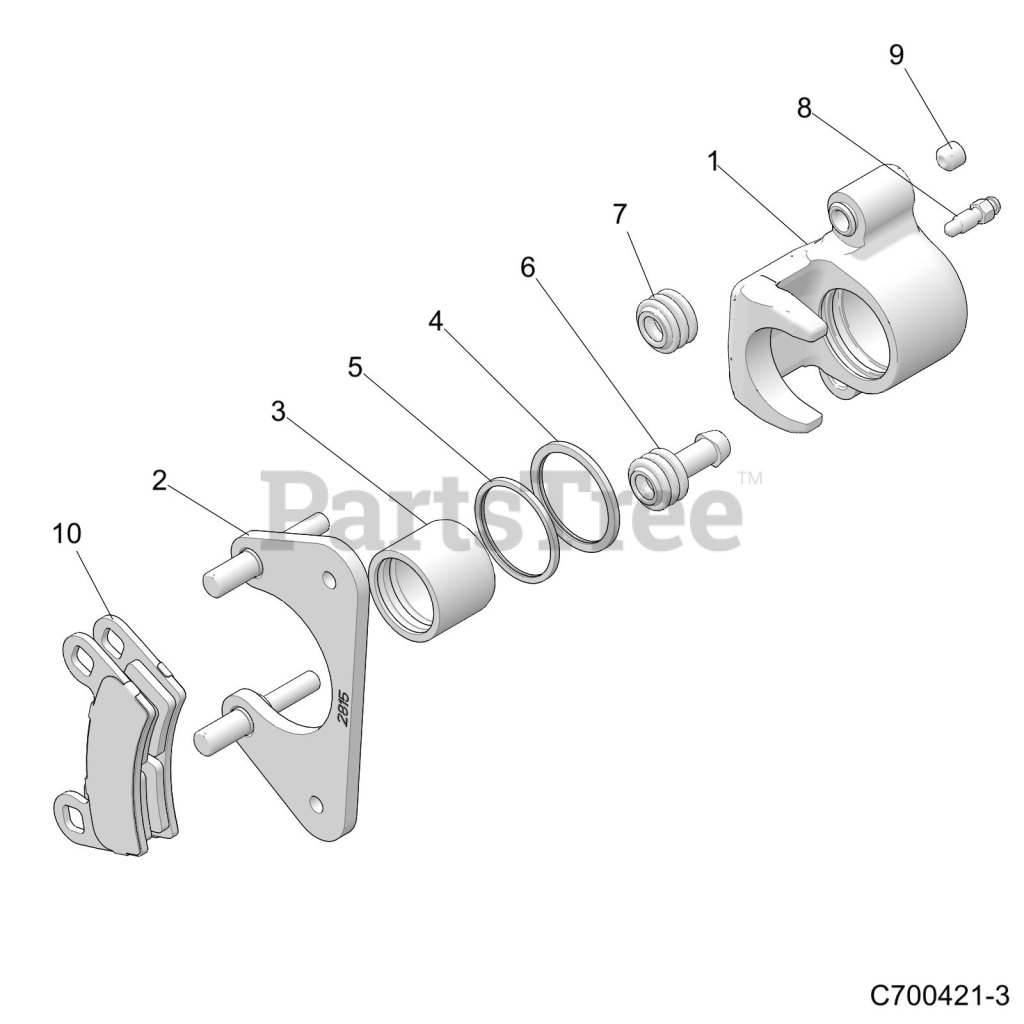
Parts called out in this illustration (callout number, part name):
1	ASM-BRK-CAL-RL-SB1.5-GROOVED
1	ASM-BRK-CAL-RR-SB1.5-GROOVED
2	ASM-CALIPER MNT,SGL BORE
3	PISTON-BRAKE,1.5,AL,GROOVED
4	SEAL-CALIPER INNER,1.50"
5	SEAL-CALIPER,OUTER,1.50"
6	BOOT-PIN BUSHING
7	BOOT-PIN SEAL
8	SCR-M7X1.0,BLEEDER,OLIVE D
9	SCR-M10X1.0X8,SOC SET-OD
10	KIT, BRAKE PAD
